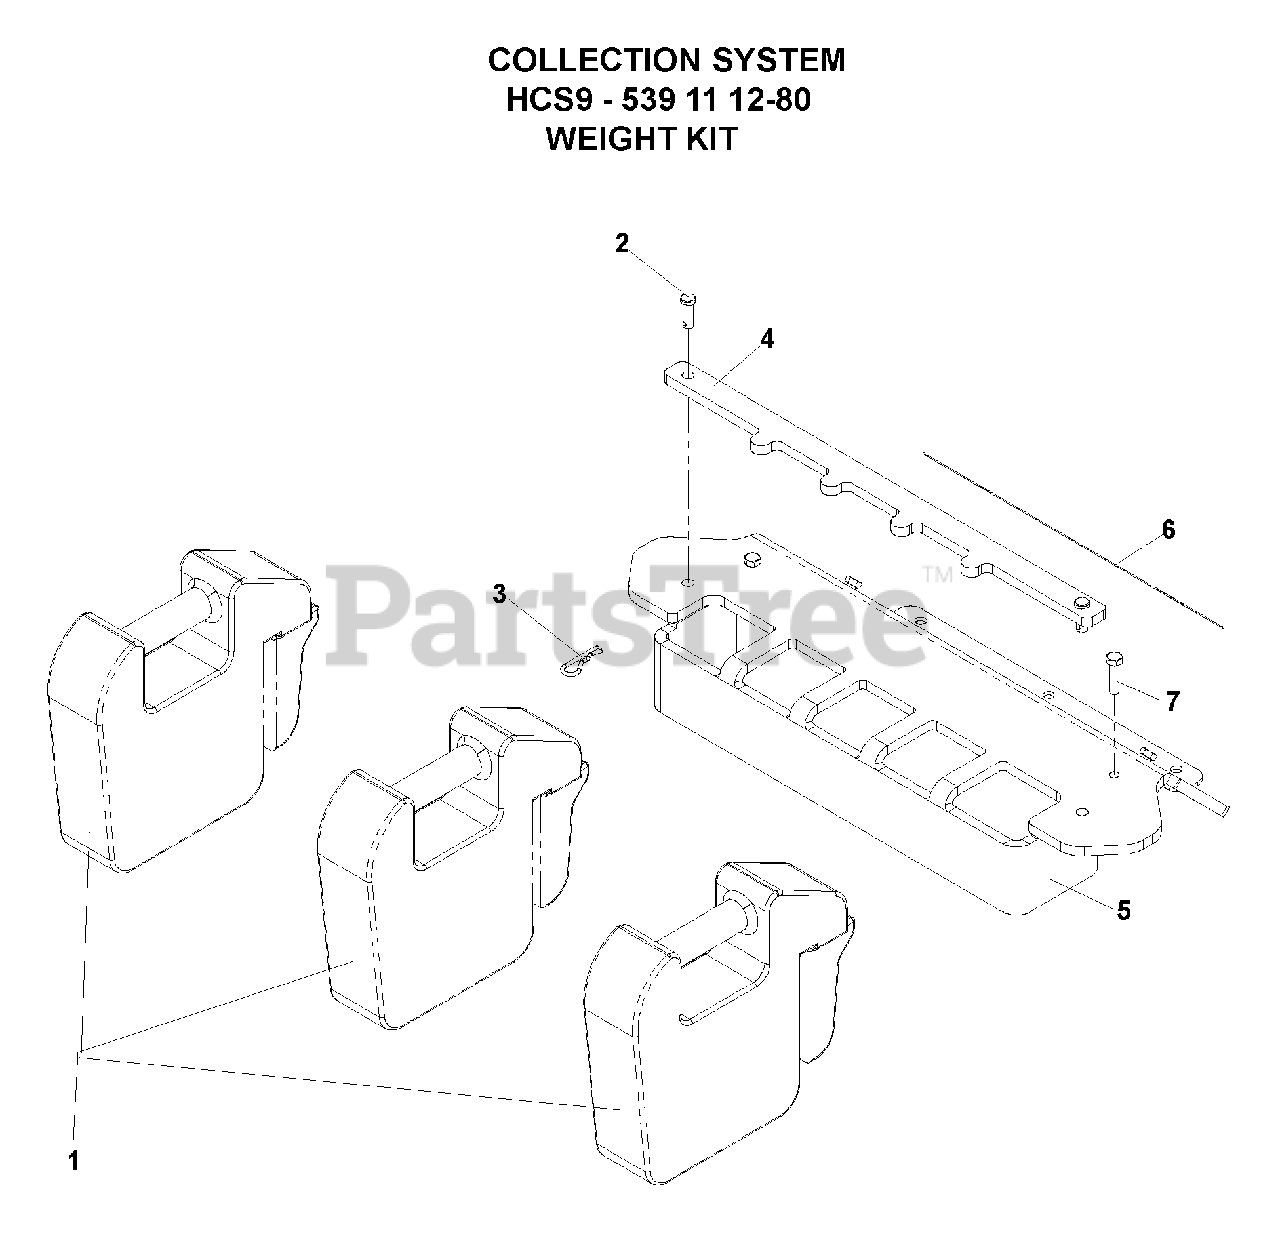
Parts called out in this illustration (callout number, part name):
1	FRONT WEIGHT
2	PIN CLEVIS, 3/8 X 1
3	PIN HAIR, 1/8 X 1 13/16
5	WEIGHT BAR
6	PAD, ABRASIVE
7	HCS, 5/16-18 X 1 1/4, GR5
539111280	Weight Kit Collection System
